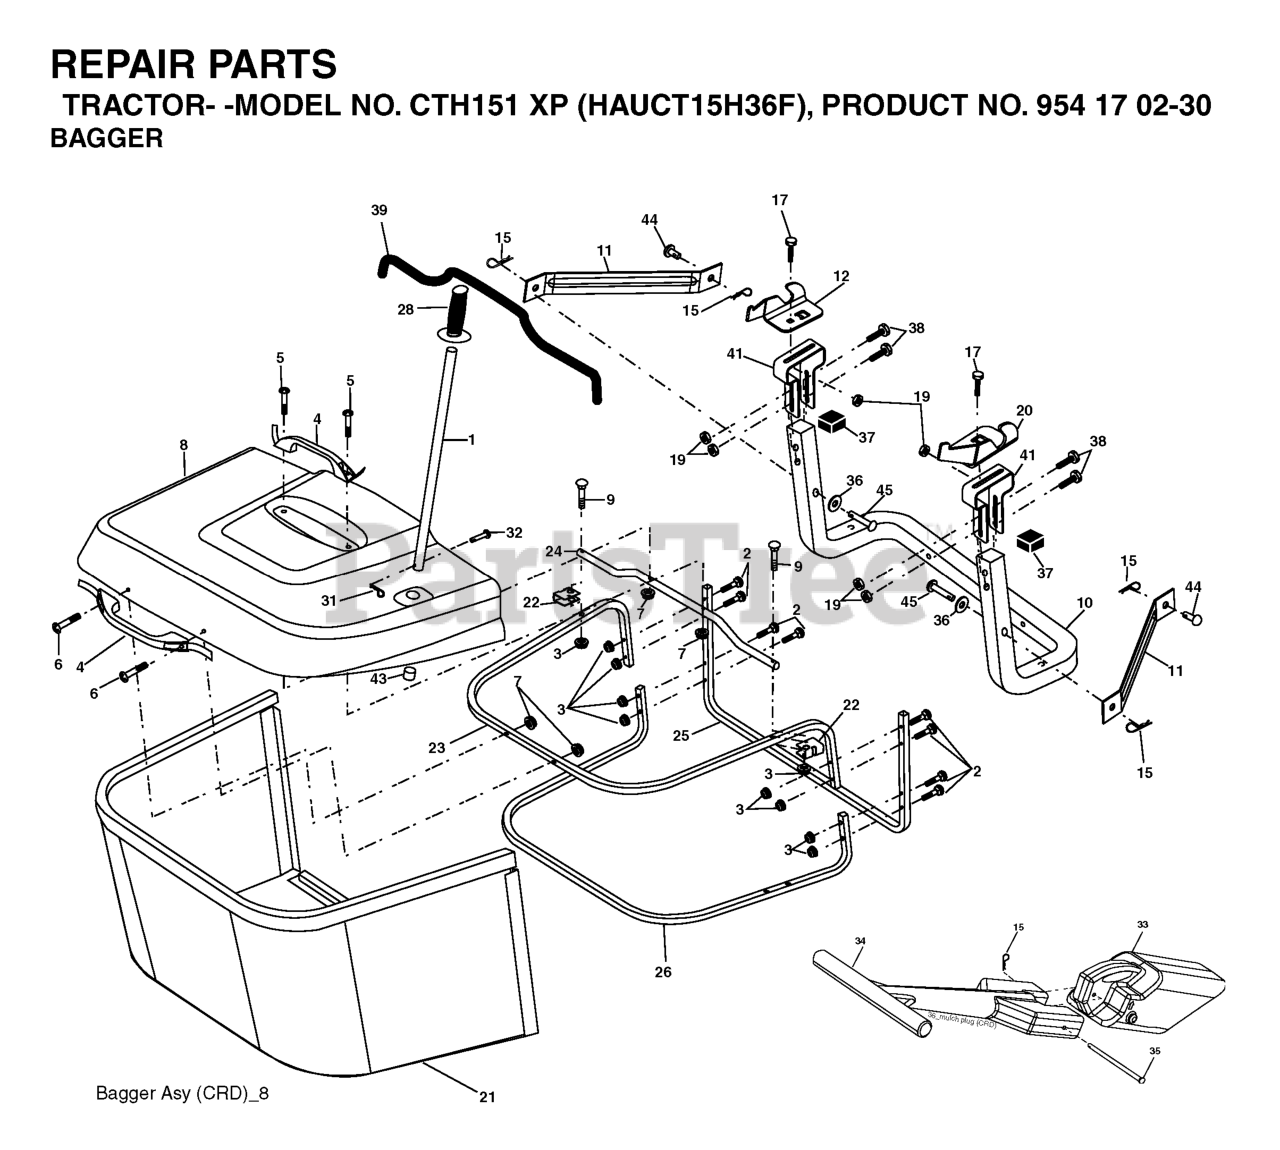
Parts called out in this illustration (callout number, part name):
1	TUBE HANDLE
2	Bolt Carriage 1/4-20 x 2.0 Gr.5
3	NUT T
4	HANDLE.BAGGER.W/LVRS.BLK.CRD
5	SCREW.PAN.HEAD
6	REPL BY 532 75 00-29
8	COVER.PNT.BGR.CRD.WSLOTS.MS668
9	Bolt Carriage 1/4-20 x 2.25d x Gr.5
10	TUBE
11	BRACKET.SUPPORT.UPPER.BAG.CRD
12	BRKT PIVOT
15	RETAINER-SPRNG RB
17	RP BOLT 5/16-18 X3/4 ZN/YEL GR
19	NUT LOCK HEX FLANGE 5/16-18
20	BRKT.PIVOT.RH.CRD
21	GRASS BAG
22	BRKT.SIDE.BAG.CRD
23	TUBE.UPPER.BAG.CRD
24	TUBE.PIVOT.BAG.CRD.BLACK
26	TUBE.LOWER.BAG.CRD
28	GRIP.HANDLE.BLACK
31	RETAINER CLIP
32	RIVET,DRILLED
33	PLUG.MULCHER.92 CRD
34	HANDLE.MULCHER.92.CRD (2 2)
36	WASHER
37	Plug Support Bagger CRD
38	BOLT.5/16-18X2.5
39	SEAL.TRIM.37'
41	BRKT.VERT.ADJ.BAGGER.CRD
43	PLUG, TUBING END
